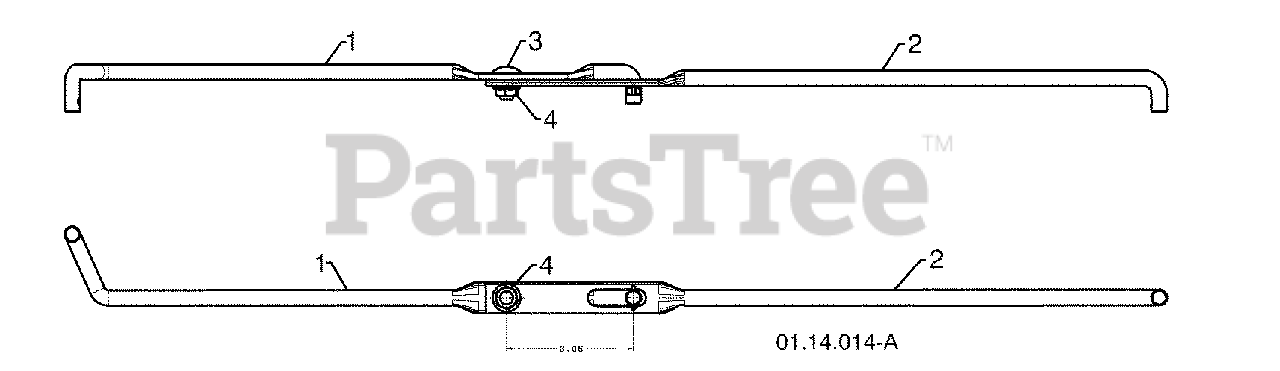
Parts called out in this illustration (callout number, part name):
1	SHIFTER ROD TOP
2	SHIFTER ROD BOTTOM
3	CARRIAGE BOLT 5/16-18 X .75
4	NUT 5/16-18
